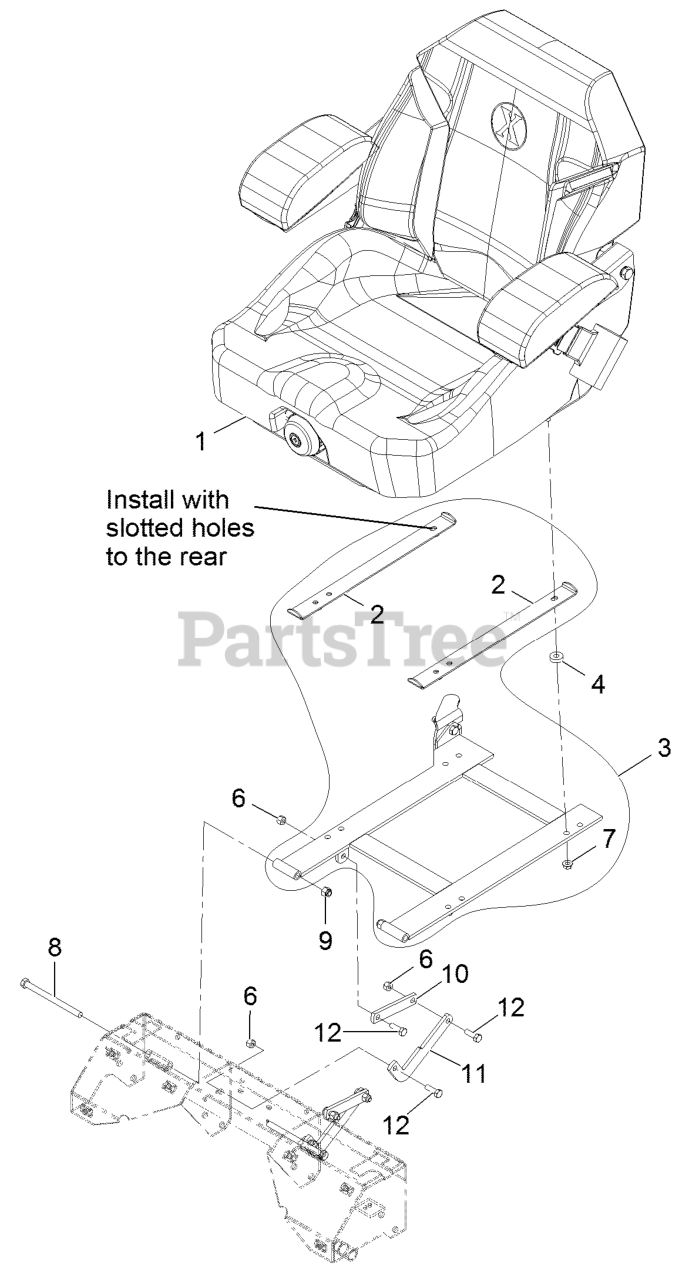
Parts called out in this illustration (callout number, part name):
1	KIT-SUSPENSION SEAT
2	STOP/SPACER-SEAT
3	KIT,SEAT FRAME SERVICE
6	NUT-LOCK, NI
8	SCREW-HH
9	NUT-LOCK, NI
10	LINK-STOP, SEAT
11	LINK-STOP, SEAT
12	SCREW-HH
